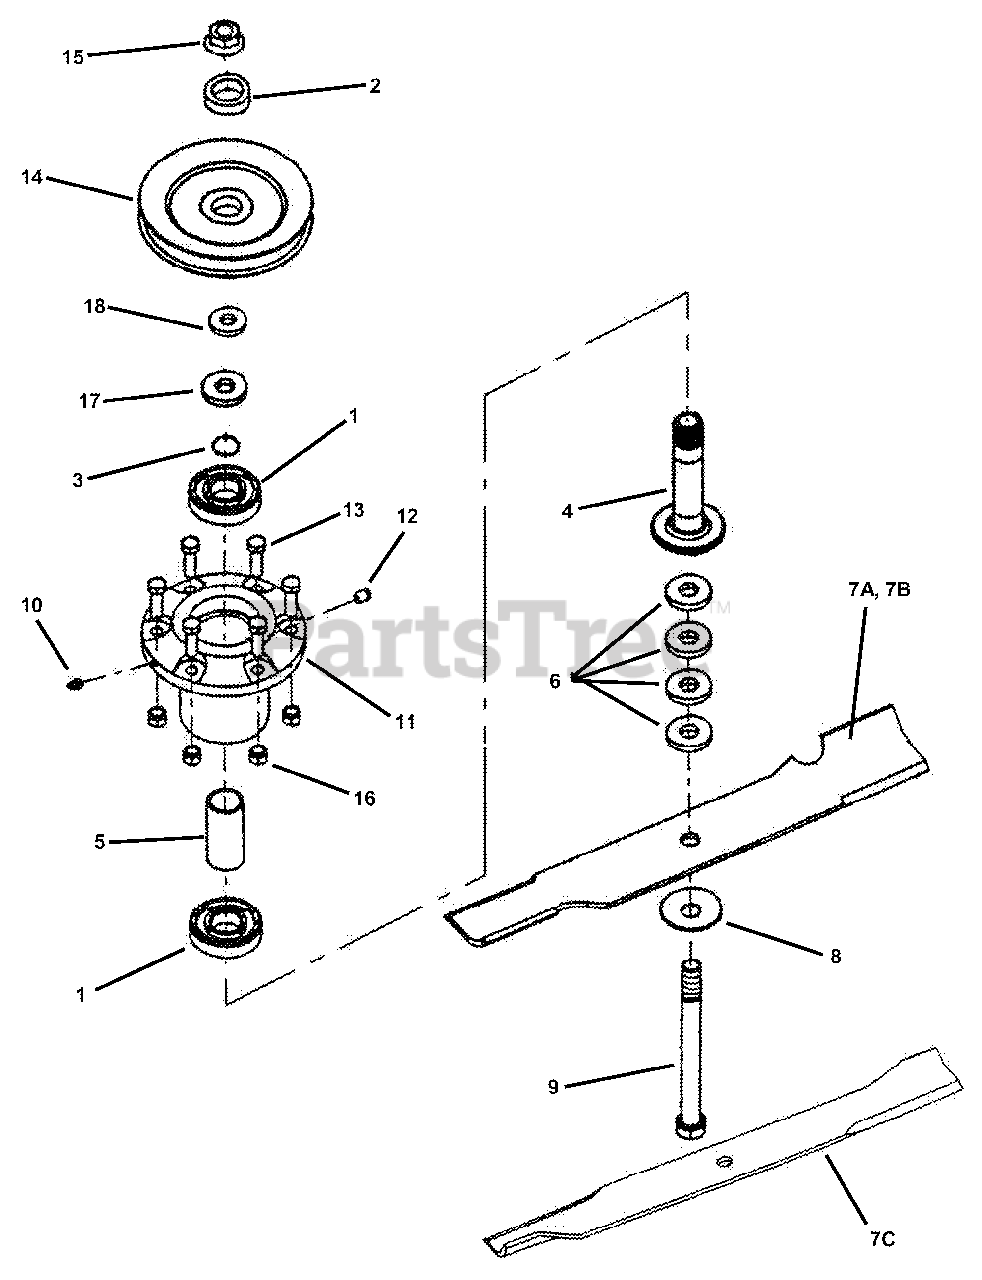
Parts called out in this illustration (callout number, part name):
1	BEARING, Sealed
2	WASHER, Spindle
3	SNAP-RING, Spindle Shaft
4	SHAFT, Spindle
5	SPACER, Bearing
6	SPACER, Blade
7A	BLADE, 21" (61" Deck) (High Lift)
7B	BLADE, 18" (52" Deck)
7C	BLADE, 21" (61" Deck) (Low Lift)
8	WASHER, Beveled
9	BOLT, 5/8-11 x 7-1/2" Hex Head Cap, Grade 5
10	LUBE FITTING, 1/4-28 Thread Forming
11	HOUSING, Cutter
12	VENT, Spindle
13	BOLT, 3/8-16 x 1-1/4" Rib Necked
14	PULLEY, 5-3/4" O.D. (61" Deck)
15	NUT, 5/8-11 Hex Flange Lock, Grade 5
16	NUT, 3/8-16 HEX NYLON LOCK
17	SEAL, Nylos
18	WASHER
